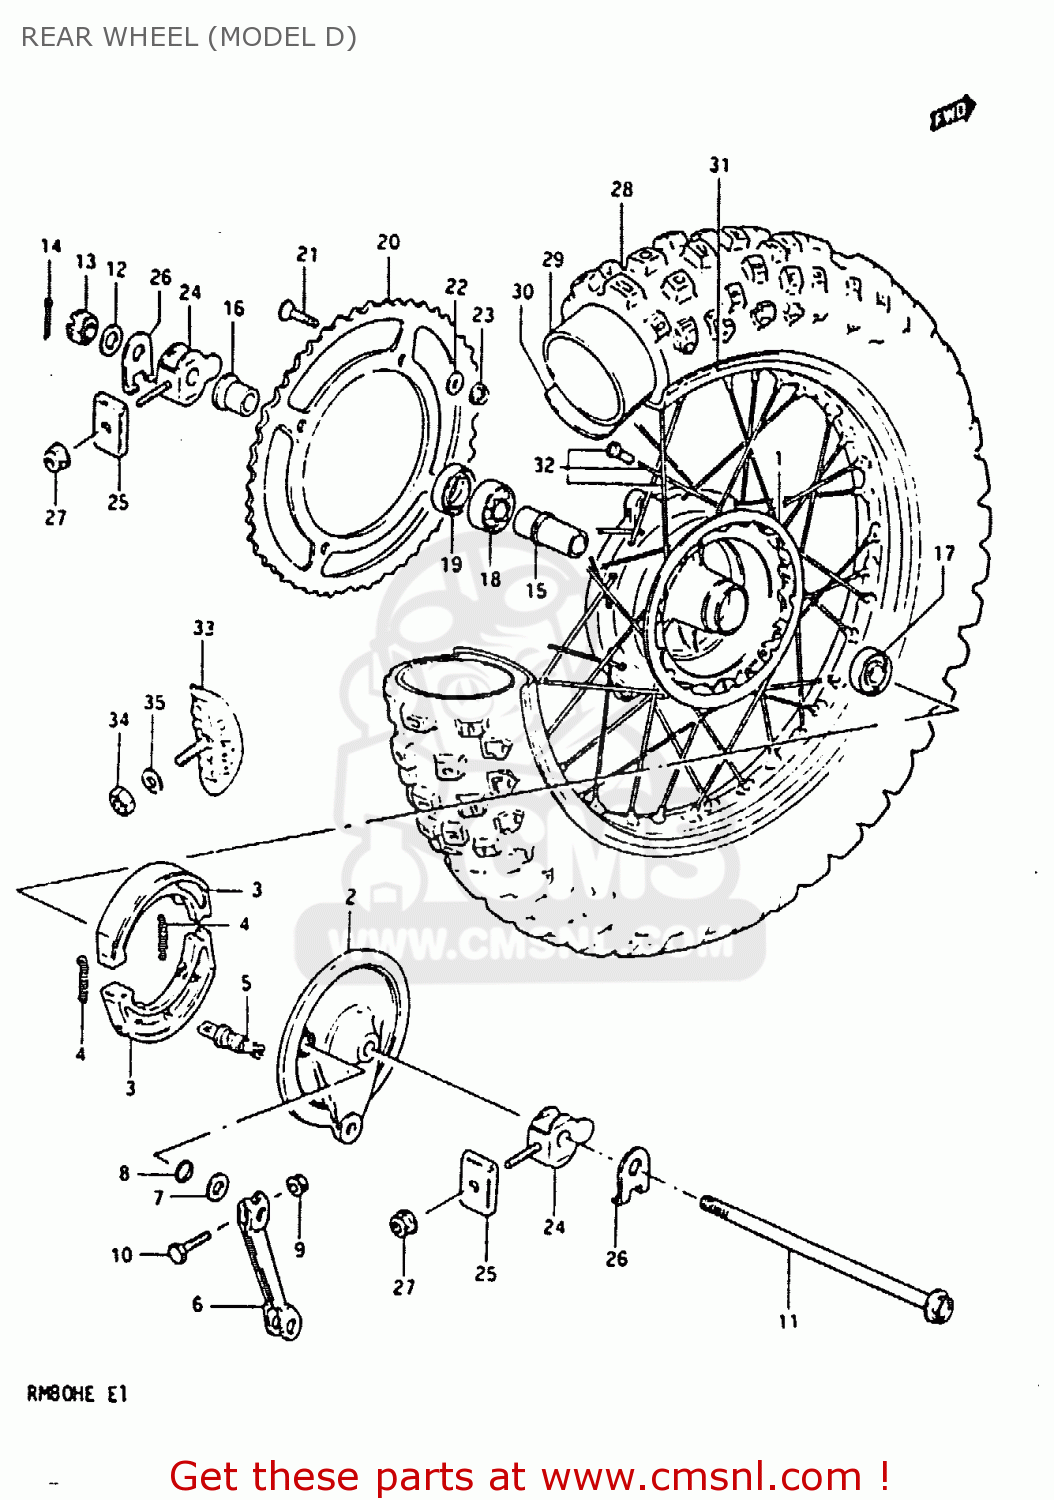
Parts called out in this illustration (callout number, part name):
1	DRUM, REAR HUB
2	PANEL, REAR HUB
3	SHOE,BRAKE
4	SPRING, BRAKE SHOE
5	CAM,FRONT BRAKE
6	LEVER,RR BRAKE CAM
7	WASHER(12.5X20X1)
8	O RING(D:2.5,ID:11.4)
9	NUT
10	BOLT
11	AXLE,REAR
12	WASHER
13	NUT 12MM
14	PIN 30X20
15	SPACER,REAR HUB BEARING
16	SPACER, AXLE LH
17	BEARING (12X32X10)
18	BEARING
19	OIL SEAL(17X38X5)
20	SPROCKET, REAR
21	SCREW(8X33.5)
22	WASHER
23	NUT
24	ADJUSTER CHAIN
25	ADJUSTER,CHAIN
26	WASHER,CHAIN ADJUSTER
27	NUT
28	TIRE, REAR (3.50*18)
29	TUBE ASSEMBLY,WHEEL,INNER
30	PROTECTOR,INNER TUBE
31	RIM, WHEEL (1.85*18 AL)
32	SPOKE ASSY,RR WHEEL
33	STOPPER,BEAD
34	NUT
35	WASHER
